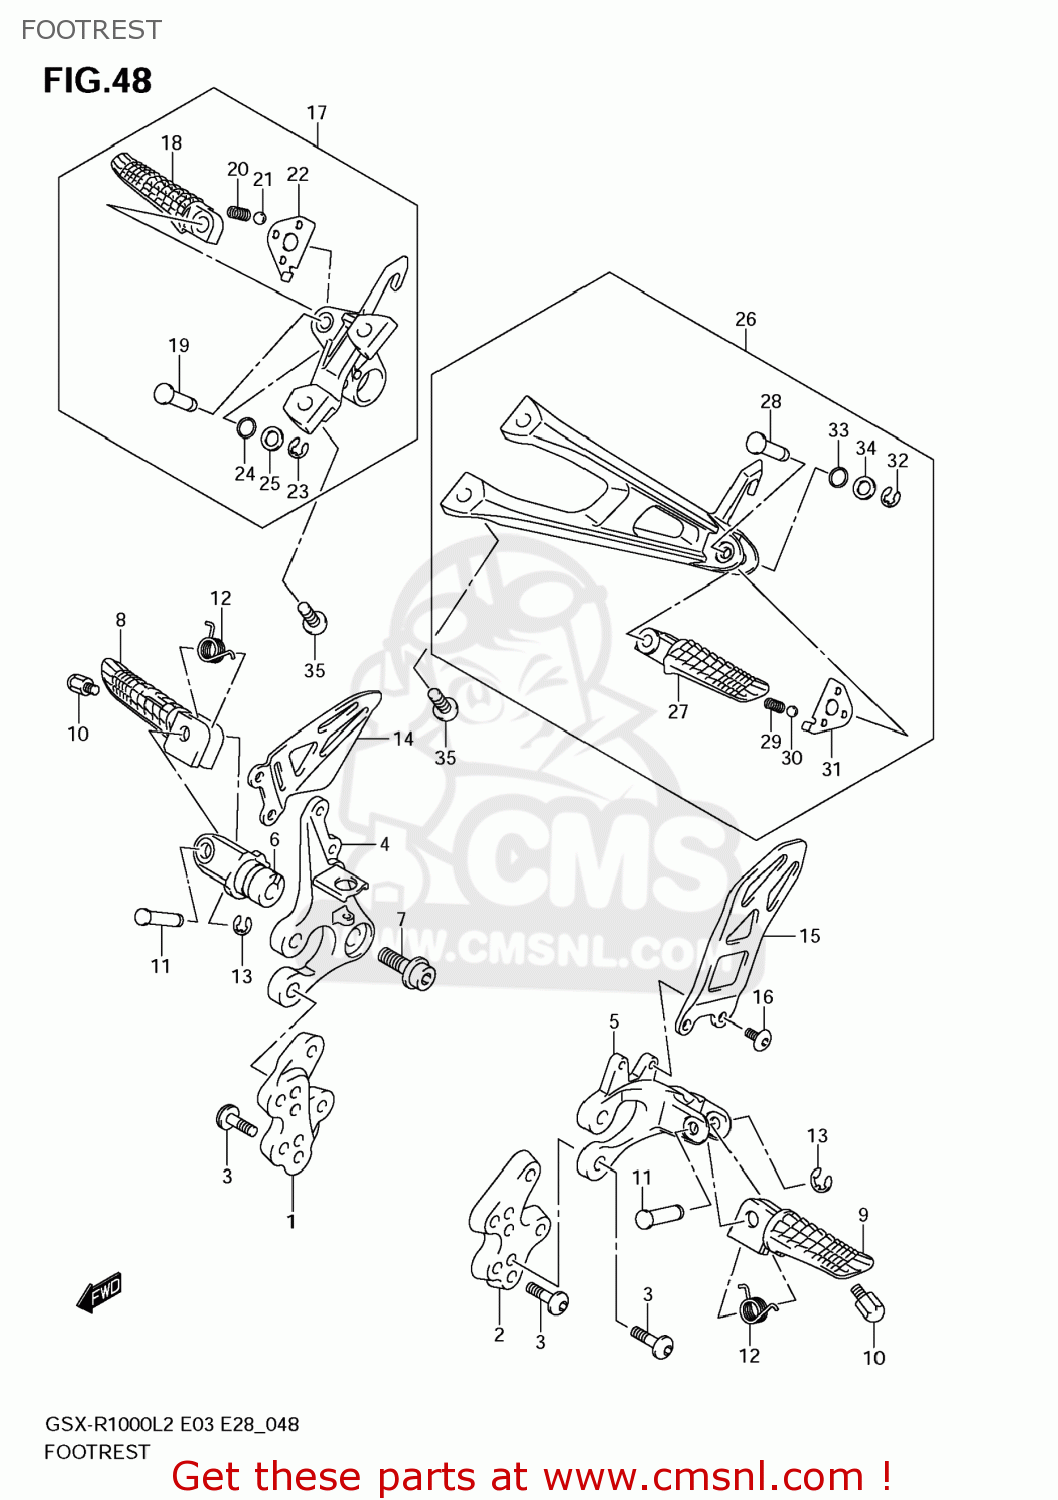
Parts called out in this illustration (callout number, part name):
1	BRACKET,FR FOOTREST NO.1,R
2	BRACKET,FR FOOTREST NO.1,L
3	BOLT(8X23)
4	BRACKET,FR FOOTREST NO.2,R
5	BRACKET,FR FOOTREST NO.2,L
6	HOLDER,FOOTREST
7	BOLT(10X28)
8	BAR,FR FOOTREST,R
9	BAR,FR FOOTREST,L
10	BOLT,BANK SENSOR
11	PIN
12	SPRING
13	E RING
14	GUARD,FR FOOTREST,R
15	GUARD,FR FOOTREST,L
16	SCREW,FOOTREST GUARD,L
17	FOOTREST ASSY,PILLION,R
18	BAR,PILLION FOOTREST,R
19	PIN
20	SPRING
21	BALL
22	PLATE,PILLION FOOTREST,R
23	E RING
24	O-RING
25	WASHER,PILLION FOOTREST
26	FOOTREST ASSY,PILLION,L
27	BAR,PILLION FOOTREST,L
28	PIN
29	SPRING
30	BALL
31	PLATE,PILLION FOOTREST,L
32	E RING
33	O-RING
34	WASHER,PILLION FOOTREST
35	BOLT(8X23)
